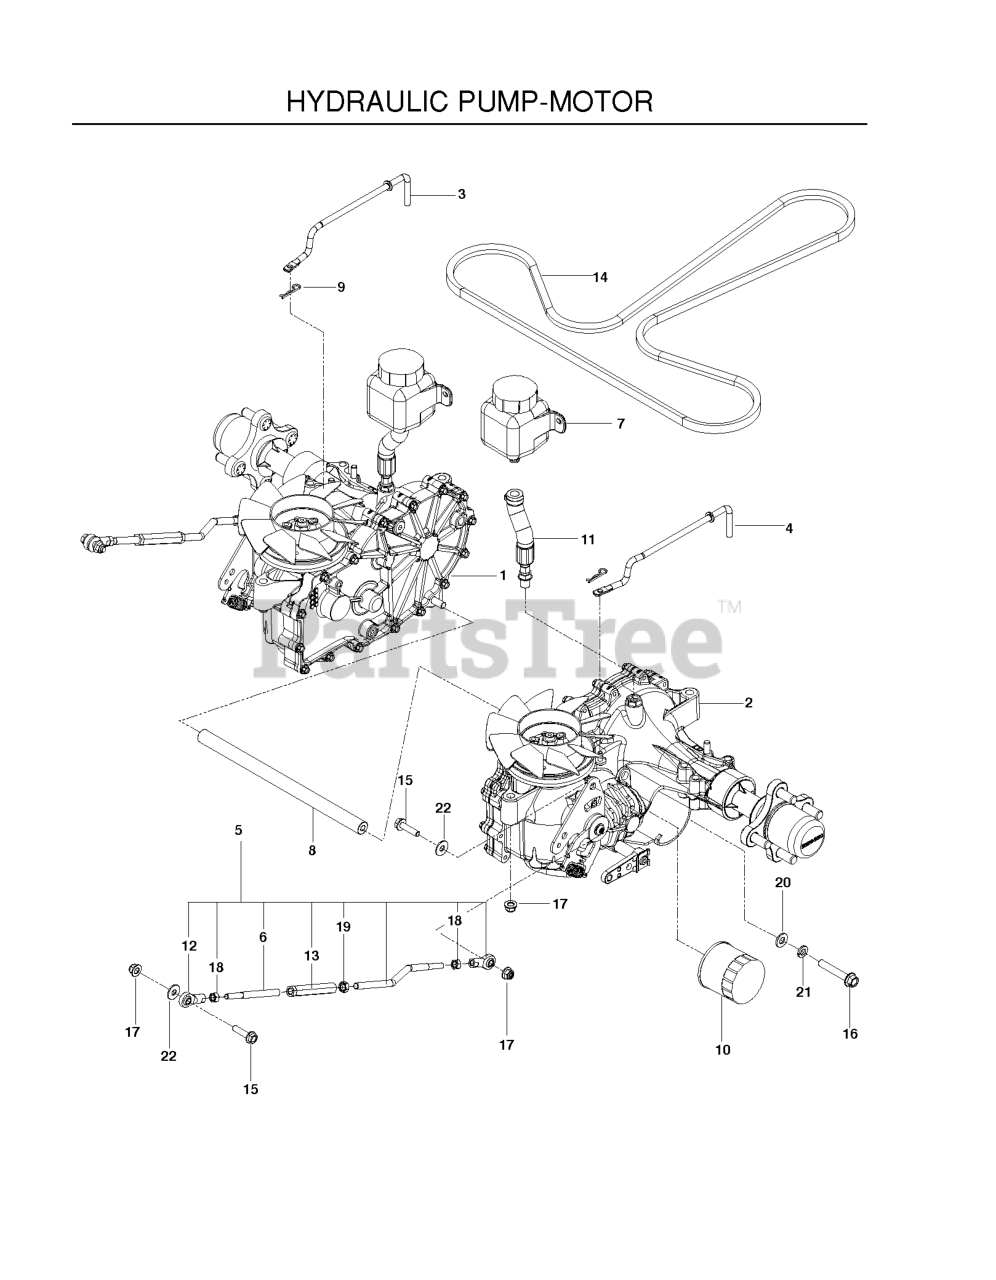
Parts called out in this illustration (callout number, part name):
1	HG_TRANS, ZT-3400, RT
2	HG_TRANS, ZT-3400, LT
3	LINKAGE, RIGHT BYPASS
4	LINKAGE, LEFT BYPASS
5	ASSEMBLY, CONTROL LINKAGE
6	LINKAGE, CONTROL, FT
7	TANK.EXPANSION.350ML 71328
8	SHAFT, TIE ROD
9	HAIRPIN #2
10	HG_FILTER, ZT4800 52114
11	ASSEMBLY, HOSE, EXPANSION
12	BALL JOINT, RIGHT HANDED
13	TURNBUCKLE, 3/8
14	BELT, "AX", 86.7"
15	HHFS 5/16-18 X 1.25 TPBLT GD 5
16	HHFS 3/8-16 X 2.25 GD 8
17	5/16-18 NYLOC FLANGE NUT
19	NUT 3/8-24 JAM
20	WASHER 3/8 SAE FLAT
21	SLW 3/8 STD
22	WASHER 5/16 FLAT
